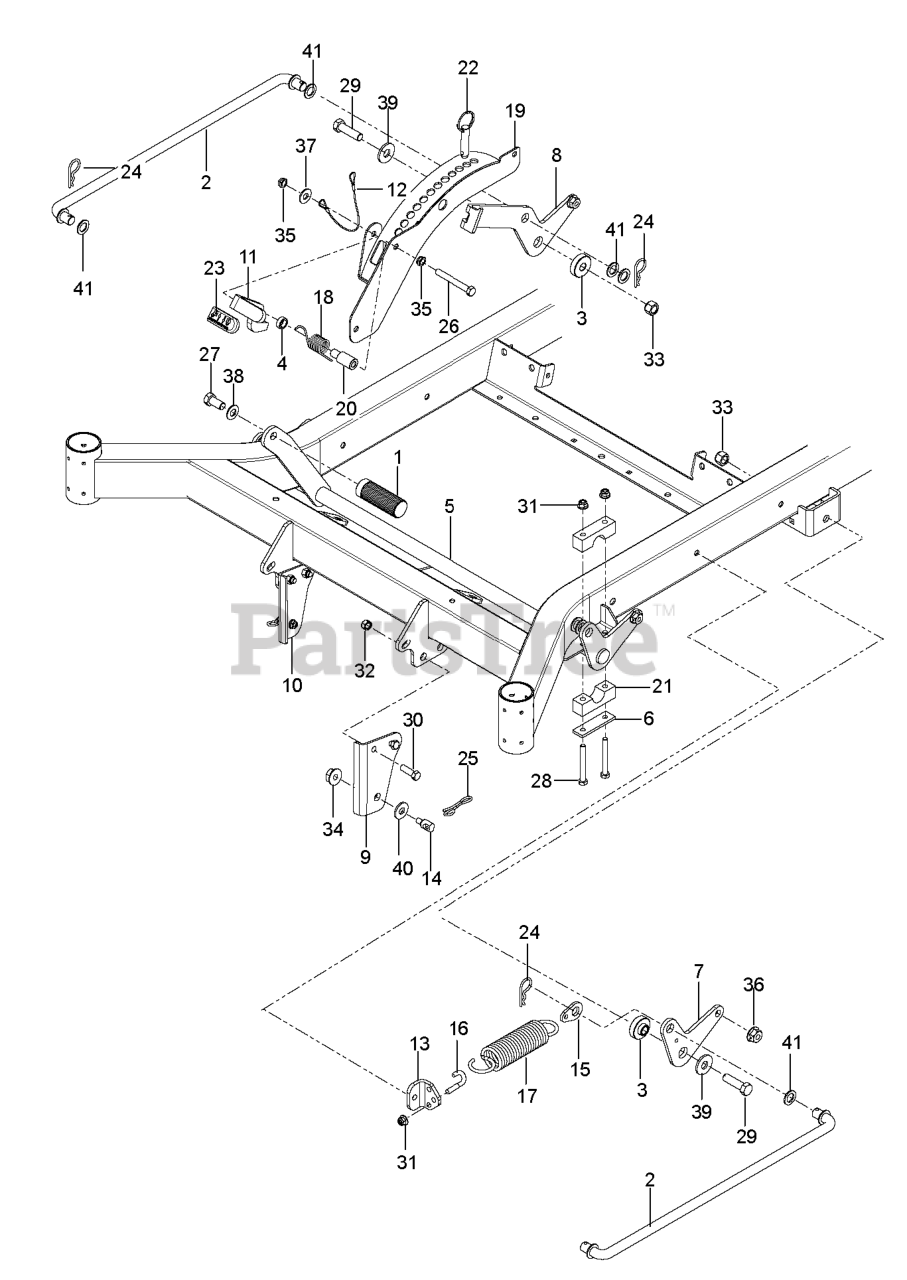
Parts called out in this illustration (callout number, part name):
1	PEDAL, DECK HEIGHT
2	CROSS LINK
3	SPACER.IDLER.METAL.POWDER
4	SPACER, .3
5	LIFT.PNT.MZ.DECK.WELD.E-DIP
6	REINFORCEMENT.PLATEX431
7	BELLCRANK, RR, LIFT
8	BELLCRANK REAR.RT BLACK X431
9	BRACKET.PNT.SUSP.CHAS.FR.LH.OR
10	BRACKET.PNT.SUSP.CHAS.FR.RH.OR
11	LATCH, TRANSPORT
14	STUD.FASTNER.W/ANTI-ROTATE
18	SPRING, TORSION
19	HEIGHT, ADJUST, DECK
20	PIVOT, LATCH, TRANSPORT
21	PILLOW BLOCK
22	PIN, 1/2 X 1 1/2, DETENT RING
23	GRIP, TRANSPORT-RELEASE
24	PIN, COTTER 1 3/4
25	PIN.COTTER.7/16.BOW TI.
26	BOLT.HEX.FIN.3/8-16 X 3.GR5
27	HHCS 1/2-13 X 1
29	HCS 1/2-13 X 1 3/4 GR 8
30	HCS 3/8-16X1.GRD.5.ZD
31	5/16-18 NYLOC FLANGE NUT
32	NUT 3/8-16 NYLOC
33	NUT.LK.W/WSH.1/2.
34	NUT LOCK HEX FLANGE 5/16-18
35	NUT HEX 3/8-16 NYLON, THIN
36	NUT 7/16-14 HEX WHIZ LK
37	RP WASHER 3/8 FLAT
38	CONTACT BELLSPR 1/2
39	WASHER.9/16 X 1 3/8 X 12 GA.
40	WASHER.CLEAR.ZINC
